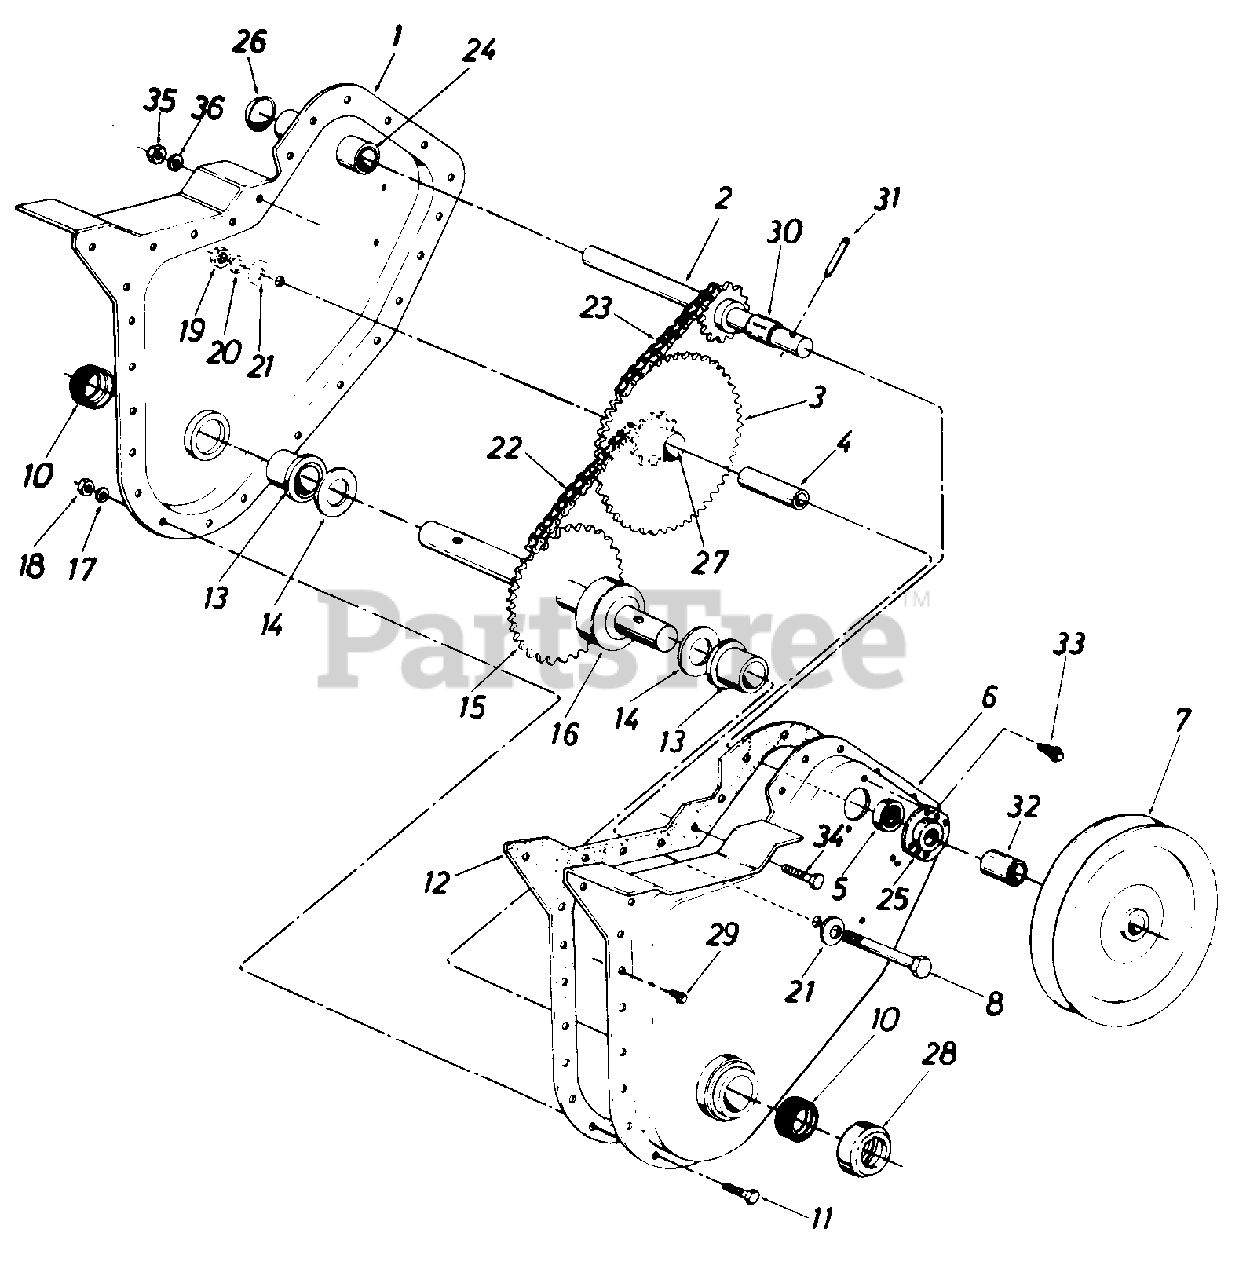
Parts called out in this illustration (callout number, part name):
1	Chain Case Ass'y. R.H.
2	Input Shaft Ass'y.
3	Hub and Sprocket Ass'y.
4	Bearing Inner Race
5	Ball Bearing
6	Chain Case Ass'y. L.H.
7	Pulley Chain Case
8	Hex Bolt 3/8-24 x 2.5" Lg.
11	Hex Bolt 1/4-28 x .625" Lg.
12	Gasket
13	Flange Brg. .879" I.D.
14	Fl-Wash. .88" I.D. x 1.5"
15	Tine Shaft Ass'y.
16	Spacer 7/8" I.D. x 2" O.D. x.68" Lg.
17	L-Wash. 1/4 I.D.
18	Hex Nut 1/4-28 Thd.
19	Hex Ins. L-Nut 3/8-24 Thd.
20	L-Wash. 3/8" I.D.
21	Bell-Wash..406" I.D.
22	Chain #4201/2" Pitch x 37 Links
23	Chain #35 .375" Pitch x 49 Links
24	Bearing .62" I.D. x .813"
25	Bearing Housing
26	Expansion Plug 13/16" Dia.
27	Bearing
28	Dust Cap
29	Hex Wash. Hd. Self-Tap Scr. 1/4-20 x .50" Lg.
30	Spacer .63" I.D. x .77" O.D. x .38" Lg.
31	Spring Pin Spiral 1/4" Dia. x 1-1/2" Lg.
32	Spacer .647 x 1.25"
33	Hex Wash. Hd. Self-Tap Scr. 1/4-20 X .38" Lg.
34	Hex Bolt 5/16-18 x .75" Lg.
35	Hex Nut 5/16-18 Thd.
36	L-Wash. 5/16" I.D.
